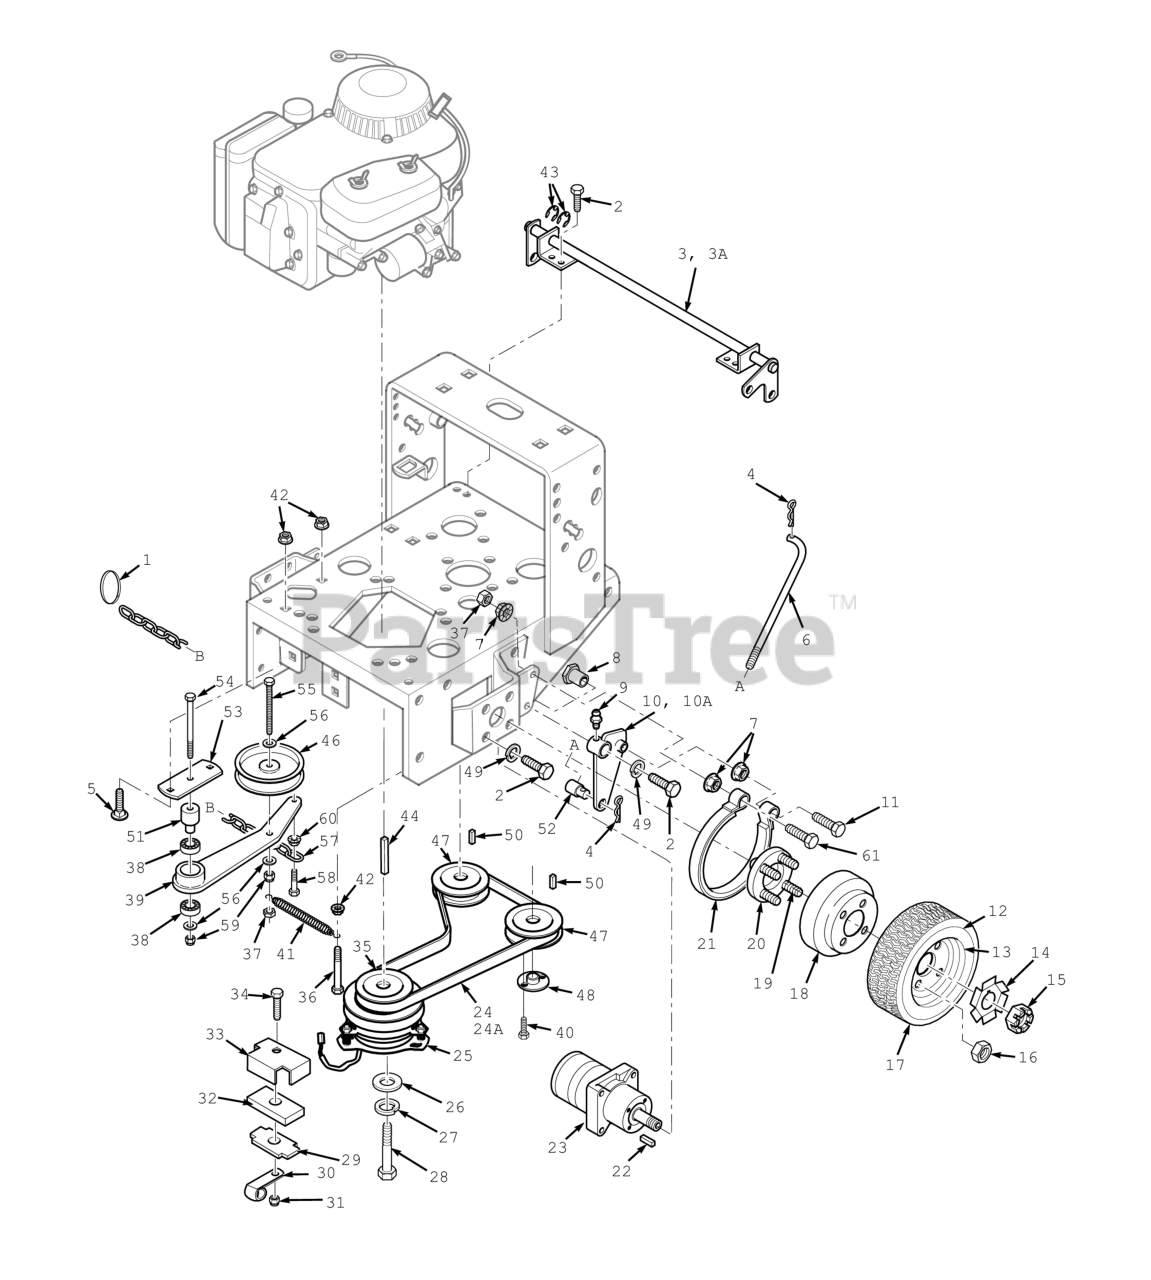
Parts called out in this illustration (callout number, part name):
1	Ring, Split
2	Bolt, Hex Head, 3/8-16 x 1 Gr. 5
3	Brake Shaft Assembly Weldment (16" Small Frame)
3A	Brake Shaft Assembly Weldment (20" Large Frame)
4	COTTER PIN, HAIR - 0.94 X 1.62
5	Bolt, 5/16-18 x .75 RHSN Carriage
6	Rod, Brake Lower
7	NUT, 3/8-16 SERRATED FLANGE HEX HEAD
8	B ushing, Brake
9	Greese Fitting, Straight 1/4 - 28
10	Brake Actuator Weldment, LH
10A	Brake Actuator Weldment, RH
11	Bolt, Hex Head 3/8-16 x 2-1/4" - 61"
12	Tire, 16 x 6.50, 4 ply
13	Rim Assy 481868 Rim Assy
14	Lock Washer, Wheel Motor
15	HEX CASTLE NUT, 3/4-28 UNEF
16	Wheel Nut, 1/2-20 x 13/16
17	Wheel Assy.,
18	Brake Drum
19	Bolt, Serr. Flange 1/2-20 x 4.563"
20	Wheel Hub Assembly
21	Brake Band Assembly
22	KEY, WOODRUFF #9, 3/16 X 3/4"
23	Wheel Motor
24	Belt, Pump Drive (16" Small Frame)
24A	Belt, Pump Drive (20" Large Frame)
25	Clutch, Electric (Ogura)
26	Flatwasher, 7/16-.469 x 1.75 x .25 (48, 52)
27	Lockwasher, 7/16� Spring
28	Bolt, Hex Head 7/16-20 x 2-3/4" w/Patch, (Kawasaki FX & FT, Yamaha MX)
29	Plate, backing Clutch Pad
30	Clamp, Cable 1/2" I.D.
31	HEX NUT, ELASTIC STOP LOCK, 5/16-18
32	Rubber Pad, Clutch Stop
33	Backing Plate, Clutch Stop
34	Bolt, Hex Head 5/16-18 x 1-1/2" - Front
35	Pulley, Pump Drive Engine
36	Bolt, Hex Head, 5/16-18 x 2.75 Zinc.
37	Bolt, Hex Head 3/8-16 x 1" Ser. Flg.
38	BEARINGS, BALL, NEUTRAL RETURN
39	Idler Arm Weldment, Pump (incl. 38)
40	Bolt, Hex Head 1/4-20 x 1" Grade 8 Black
41	Spring, Transmission Idler
42	Nut, Serrated Flange 5/16-18 (Right Front Engine Mounting, Briggs and Kohler Only)
43	RETAINING RING, 3/4" EXTERNAL "E"
44	Key, 1/4 x 1/4 x 3-3/4"
45	Flatwasher, 3/8" Special (.391 x .938 x .105)
46	Pulley, Idler 4-1/2"
47	Pulley, 5.45 OD - Tapered Bore"
48	Hub, Tapered, 15mm Bore
49	Lockwasher, 3/8" Spring, Kawasaki FX / FT & FT-EFI / B&S 32BV
50	KEY, 5 MM X 5 MM X 25 MM
51	Pivot, Idler Long - 52"
52	SWIVEL JOINT, SPEED CONTROL ROD
53	Pivot Weldment, Idler
54	Bolt, Hex Head 3/8-16 x 3" - 52"
55	Bolt, Hex Head 3/8-16 x 2-3/4" Full Thread
56	Flatwasher, 3/8 (.391 x .938 x .105 HD) Grade 8
57	Chain
58	SERR. FLG. HEX HEAD CAPSCREW, 5/16-18 X 3/4
59	HEX NUT, ELASTIC STOP LOCK, 3/8-16
60	NUT, 1/4-20 SERRATED FLANGE HEX HEAD
61	Bolt, Hex Head 3/8-16 x 2-1/4"
